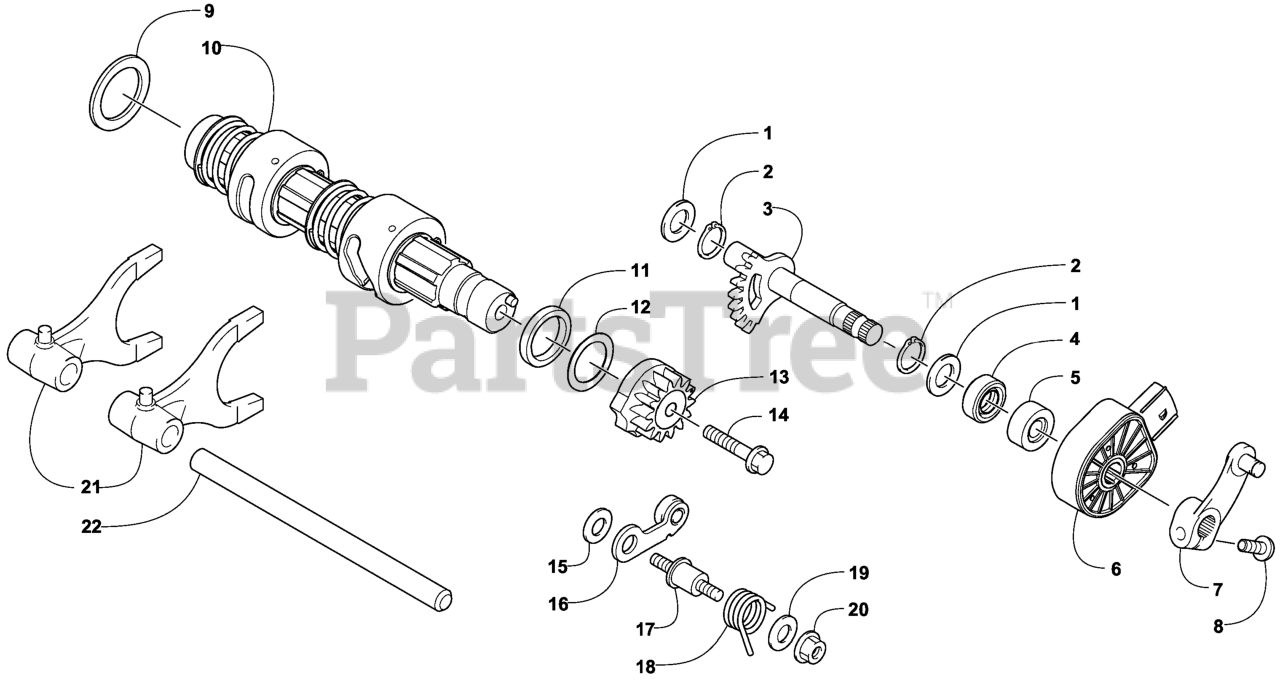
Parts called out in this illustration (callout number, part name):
1	WASHER-STEEL
2	RING-RETAINING, EXTERNAL
3	SHAFT-ROOSTER
4	SEAL-GEAR SHIFT
5	SPACER-OUTER, SHIFT SELEC
6	SWITCH-GEAR, ENGINE
7	GEAR SELECT ARM ASM
9	WASHER-STEEL
10	SHAFT-GEAR SHIFT
11	SPACER-SHIFT SHAFT
12	WASHER-STEEL
13	CAM-DETENT, GEAR SHIFT
14	SCREW-HFH
15	WASHER-STEEL
16	STOPPER-SWING ARM, CAM
17	SUPPORT-CAM, STOPPER
18	SPRING-TORSION, CAM ARM
19	WASHER-STEEL
20	NUT-HHF
21	FORK-SHIFT
22	SHAFT-SHIFT FORK
